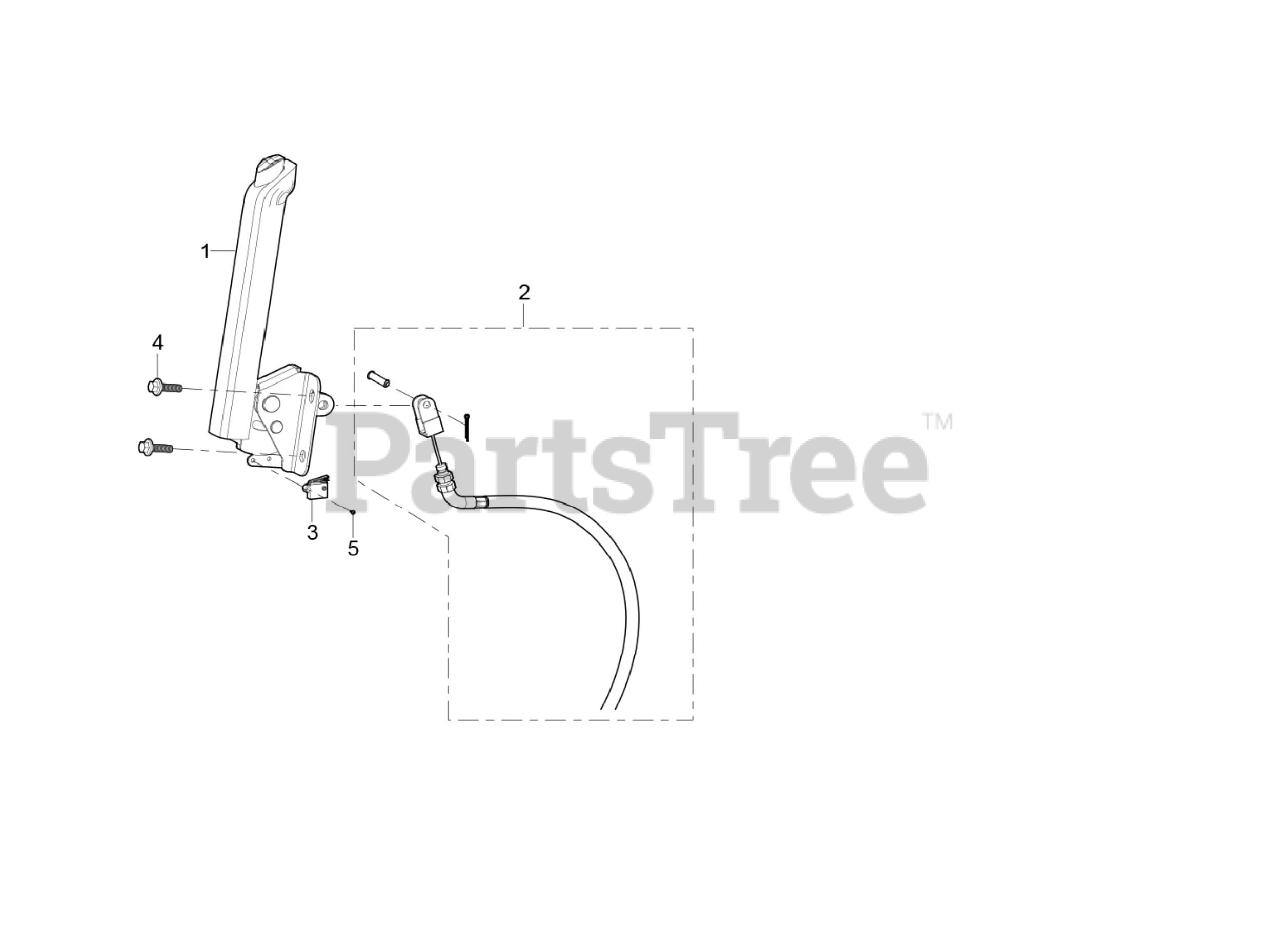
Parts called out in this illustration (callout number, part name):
1	PARKING BRAKE ASSEMBLY
2	PARKING BRAKE CABLE x
3	PARKING BRAKE SWITCH
4	Cross Large Plate Head Screw M8x16
5	CROSS HEAD SCREW M3x12
